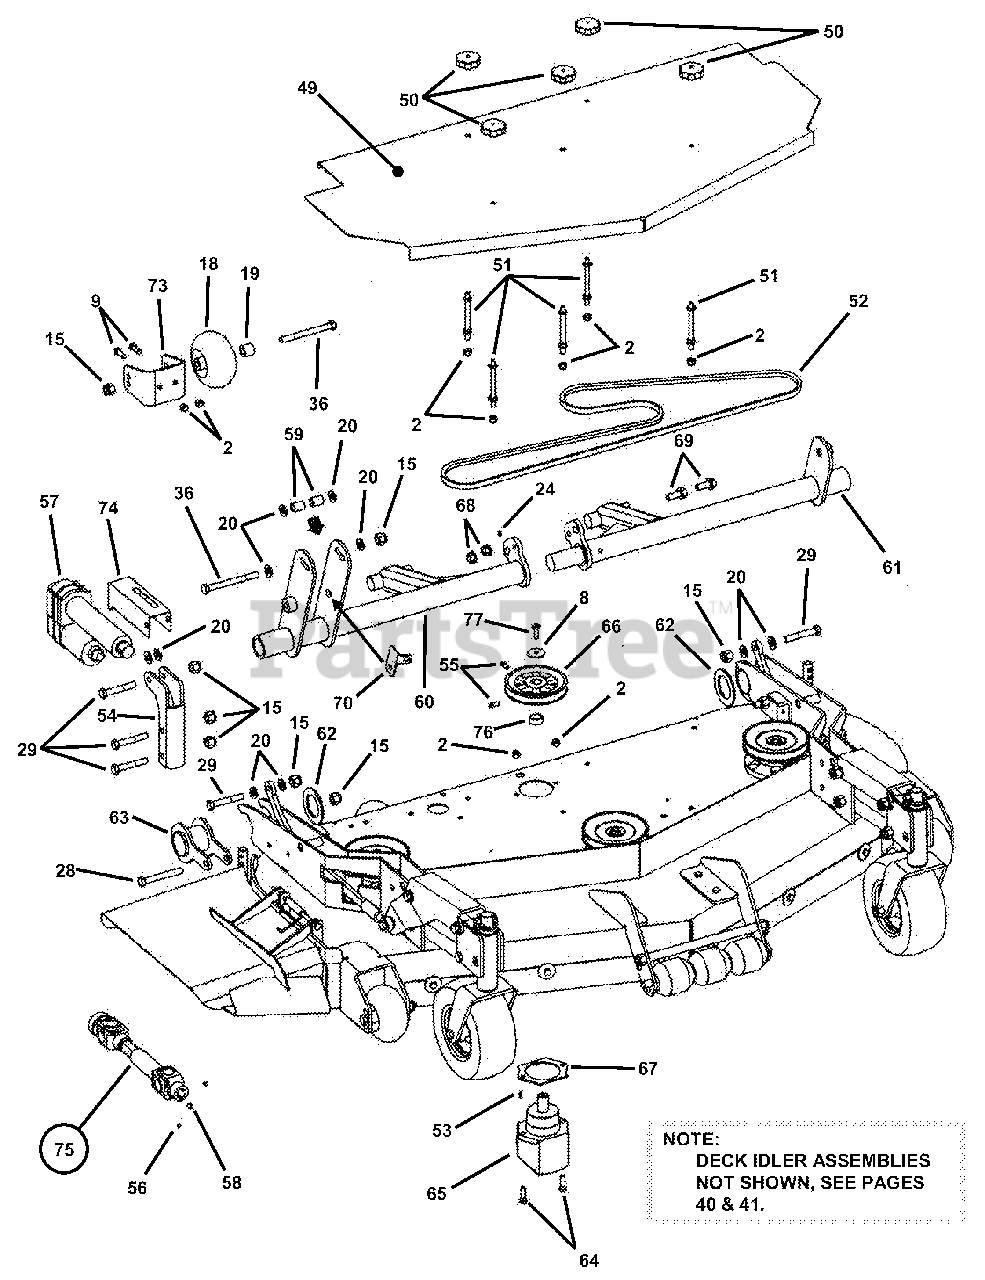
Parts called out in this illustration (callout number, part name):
2	NUT, 3/8-16 HEX NYLON LOCK
8	WASHER, 13/32 x 1-1/2" Flat
9	BOLT, 3/8-16 X 1" GD5 CZ
15	NUT, 1/2-13 Hex Nyloc
18	WHEEL, Gage
19	SPACER, Gage Wheel
20	WASHER, 1/2" Flat
24	FITTING, Lube 1/4-28 Straight
28	BOLT, 1/2-13 x 3-3/4" Hex Head Cap, Grade 5
29	BOLT, 1/2-13 X 3" GD5 CZ
36	BOLT, 1/2-13 X 5 GD5 YZ
49	COVER, 52" Deck
50	KNOB, 5/16-18 Thread
51	STANDOFF, 3-1/2"
52	V-BELT, 52" Deck (122") HB
53	KEY, #6 x 5/8" Woodruff
54	MOUNT, Motor (Front)
55	SCREW, 5/16-18 x 5/8" Square Head Set w/locking patch
56	SCREW, 3/8-16 x 3/8" Hex Recess Set
57	SCREWJACK, Warner Electric 1000 lbs.
58	KEY, #9 Woodruff
59	SPACER, Motor, Rear
60	MAIN LINK (Weldment)
61	MAIN LINK (Weldment) Left Hand
62	SPACER, Tube
63	HOLDER, Pivot (Weldment)
64	BOLT, 3/8-16 X 1-1/4" GD5 CZ
65	GEARBOX, Right Angle (Peerless P/N 1000-52)
66	PULLEY, Cast 5.75" Outside Diameter
67	SHIM, Gearbox
68	NUT, 1/2-13 Hex Flange Lock, Grade 5
69	BOLT, 1/2-13 x 1-1/4" Hex Flange Lock, Grade 5
70	BRACKET, Strain Relief
73	BRACKET, Gage Wheel
74	INDICATOR, Height-of-Cut
75	ASSEMBLY, Telescoping Drive Shaft
76	SPACER
77	SCREW, 3/8-24 x 1" Hex Head Cap, Grade 5
